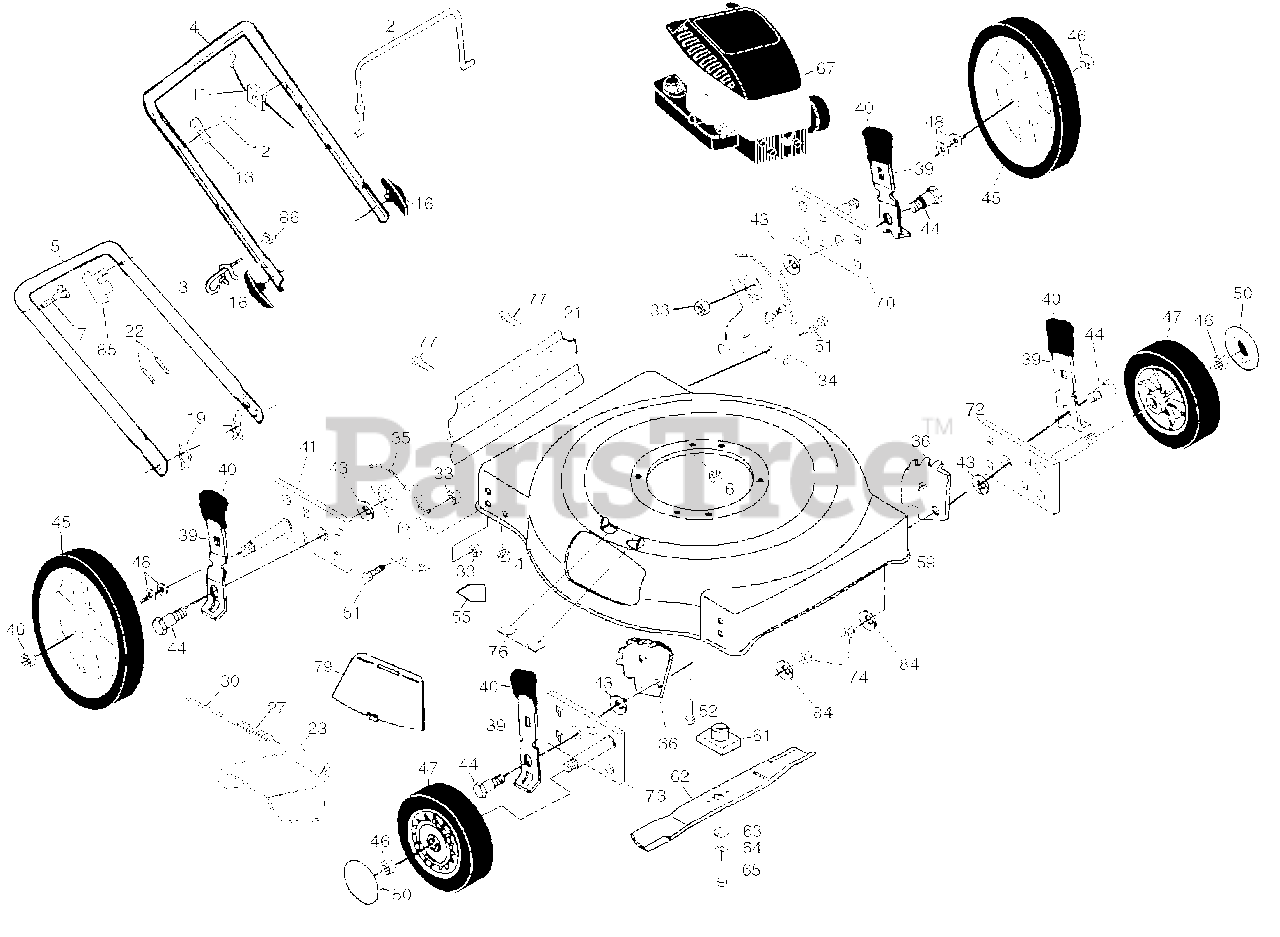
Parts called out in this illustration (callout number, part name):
1	Locknut 1/4-20
2	Control Bar
3	Rope Guide
4	Upper Handle
5	Lower Handle
7	Handle Bolt 5/16-18
11	Engine Zone Control Cable
12	Hex Washer Head Screw #10-24 x 1/2
13	Up-Stop Bracket
16	Handle Knob
19	Hairpin Cotter
21	Rear Deflector
22	Wire Tie
23	Discharge Guard
27	Torsion Spring
30	Hinge Rod
33	Locknut 5/16-18
34	Wheel Bracket Support (Left)
35	Wheel Bracket Support (Right)
36	Wheel Bracket Adjuster
39	Selector Spring
40	Selector Knob
41	Axle Arm Assembly (RR)
43	Washer
44	Shoulder Bolt
45	Wheel Assembly (Rear)
46	Locknut 1/16-18
47	Wheel Assembly (Front)
48	Washer
50	Hubcap
51	Hex Head Bolt 5/16-18
52	Hex Head Thread Rolling Screw 3/8-16 x 1
55	Danger Decal
59	Lawn Mower Housing
61	Blade Adapter
62	22" Blade
63	Hardened Washer
64	Helical Lockwasher 3/8
65	Screw Hex Head 3/8-24 x 1-3/8 (Grd. 8)
67	Engine, Briggs & Stratton
70	Axle Arm Assembly (LR)
72	Axle Arm Assembly (LF)
73	Axle Arm Assembly (RF)
74	Nut
76	Clip, Closeout
77	Screw
79	Mulch Plate
85	Bracket, Anti-Fold
